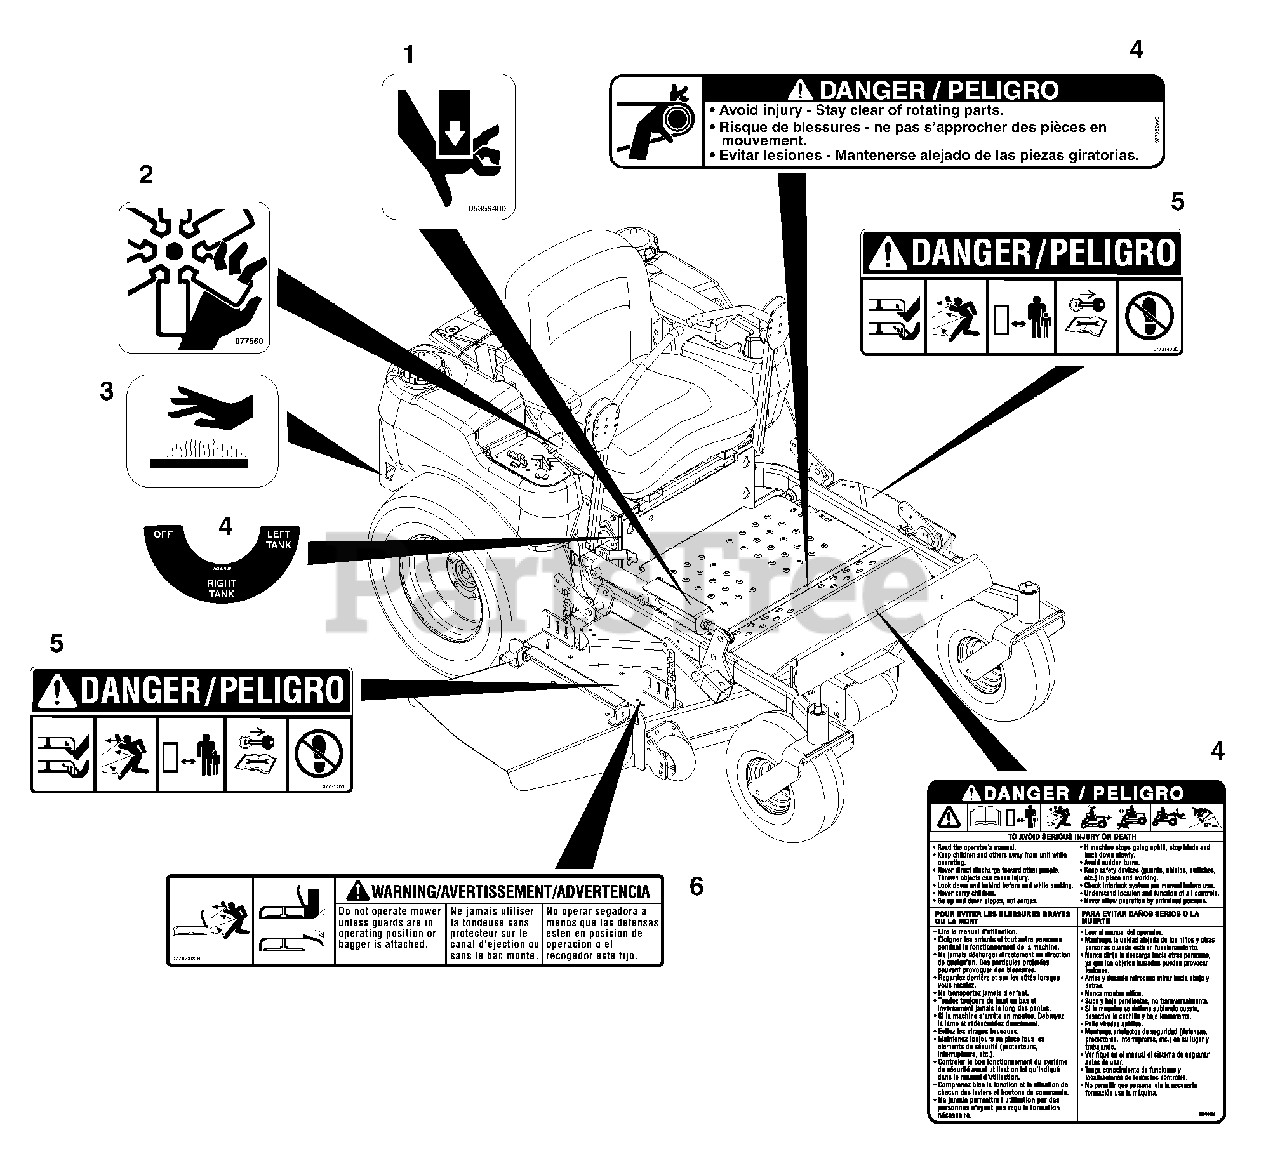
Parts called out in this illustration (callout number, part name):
1	Decal, Pinch Point
2	Decal, Danger Fan
3	Decal, Hot Surface
4	Set, Decal-Common Danger/Fuel
5	Decal, Mower Pan Head Danger
6	Decal, Warning
